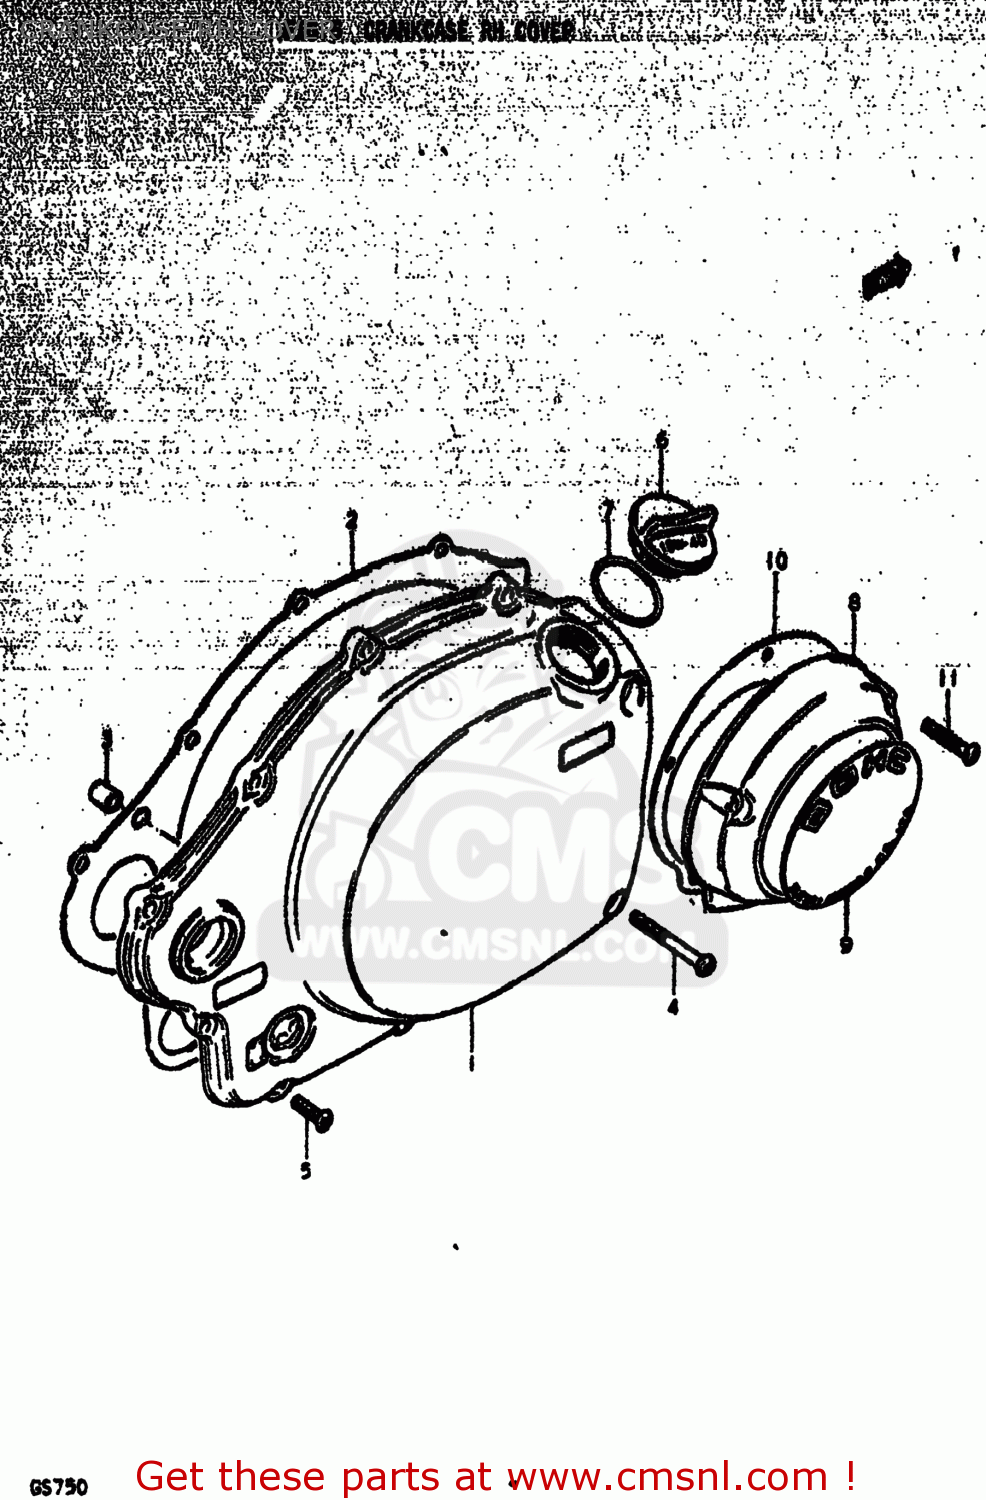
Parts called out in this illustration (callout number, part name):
1	COVER,CLUTCH
2	GASKET,CLUTCH COVER (MCA)
3	PIN
4	SCREW
5	SCREW
6	CAP
7	O RING(D:2.2,ID:32)
8	COVER,CONTACT BREAKER
9	EMBLEM
10	GASKET,CONTACT BREAKER COVER (NAS)
11	SCREW
